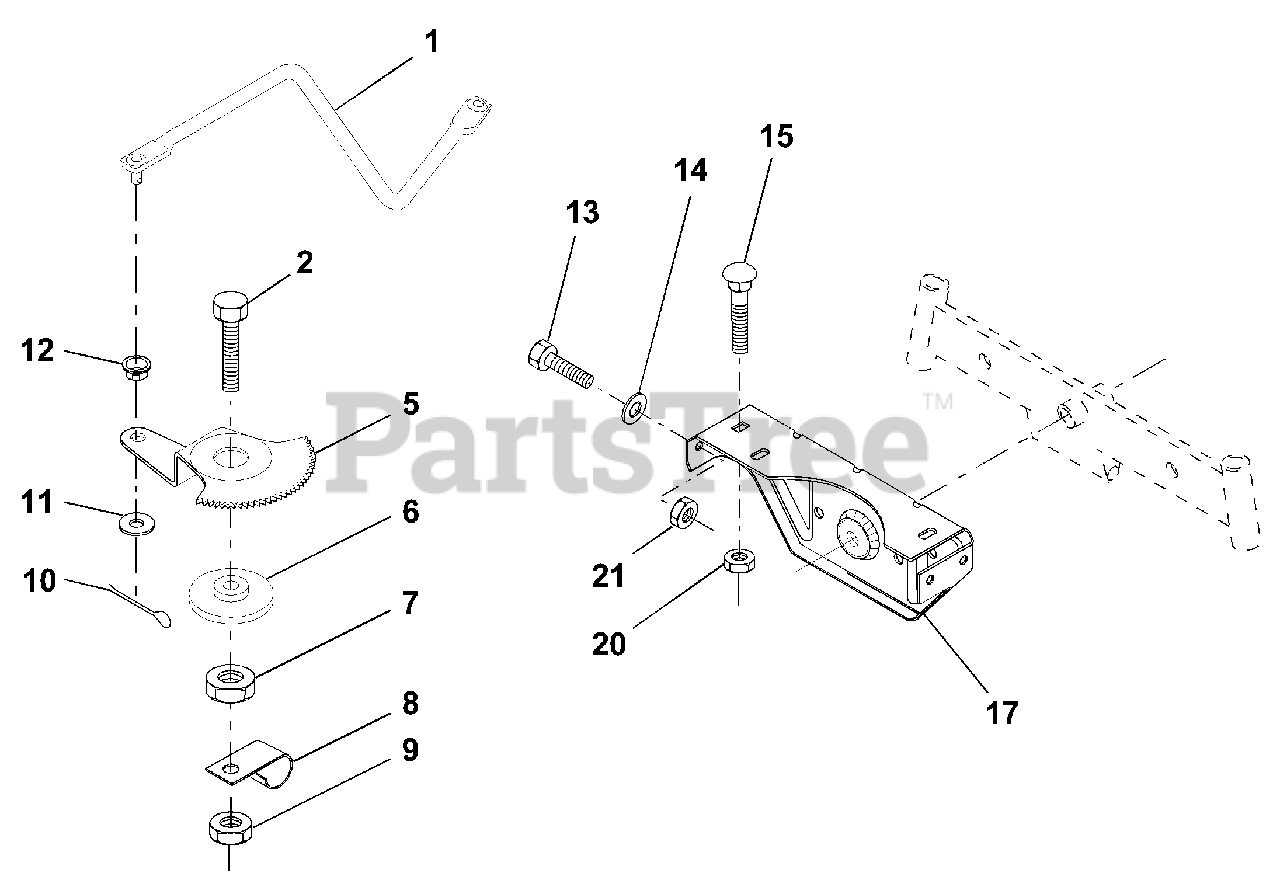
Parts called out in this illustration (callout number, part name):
1	Link, Drag
2	Bolt, Hex, Fin. 1/2-13 x 1-3/4
5	Gear, Sector
7	Nut, Heavy Hex, Top Lock 1/2-13 UNC
8	Clip, Insulated
9	Nut, Crownlock 3/8-16
10	Pin, Cotter 1/8 x 3/4
11	Washer 13/32 x 13/16 x 16 Gauge
13	Bolt, Hex Head 5/16-18 UNC x 1
14	Washer 11/32 x 7/8 x 16 Gauge
15	Bolt, Carriage 3/8-16 UNC x 3/4
17	Support, Front Axle
20	Nut, Crownlock 3/8-16
21	Nut, Crownlock 5/16-18
